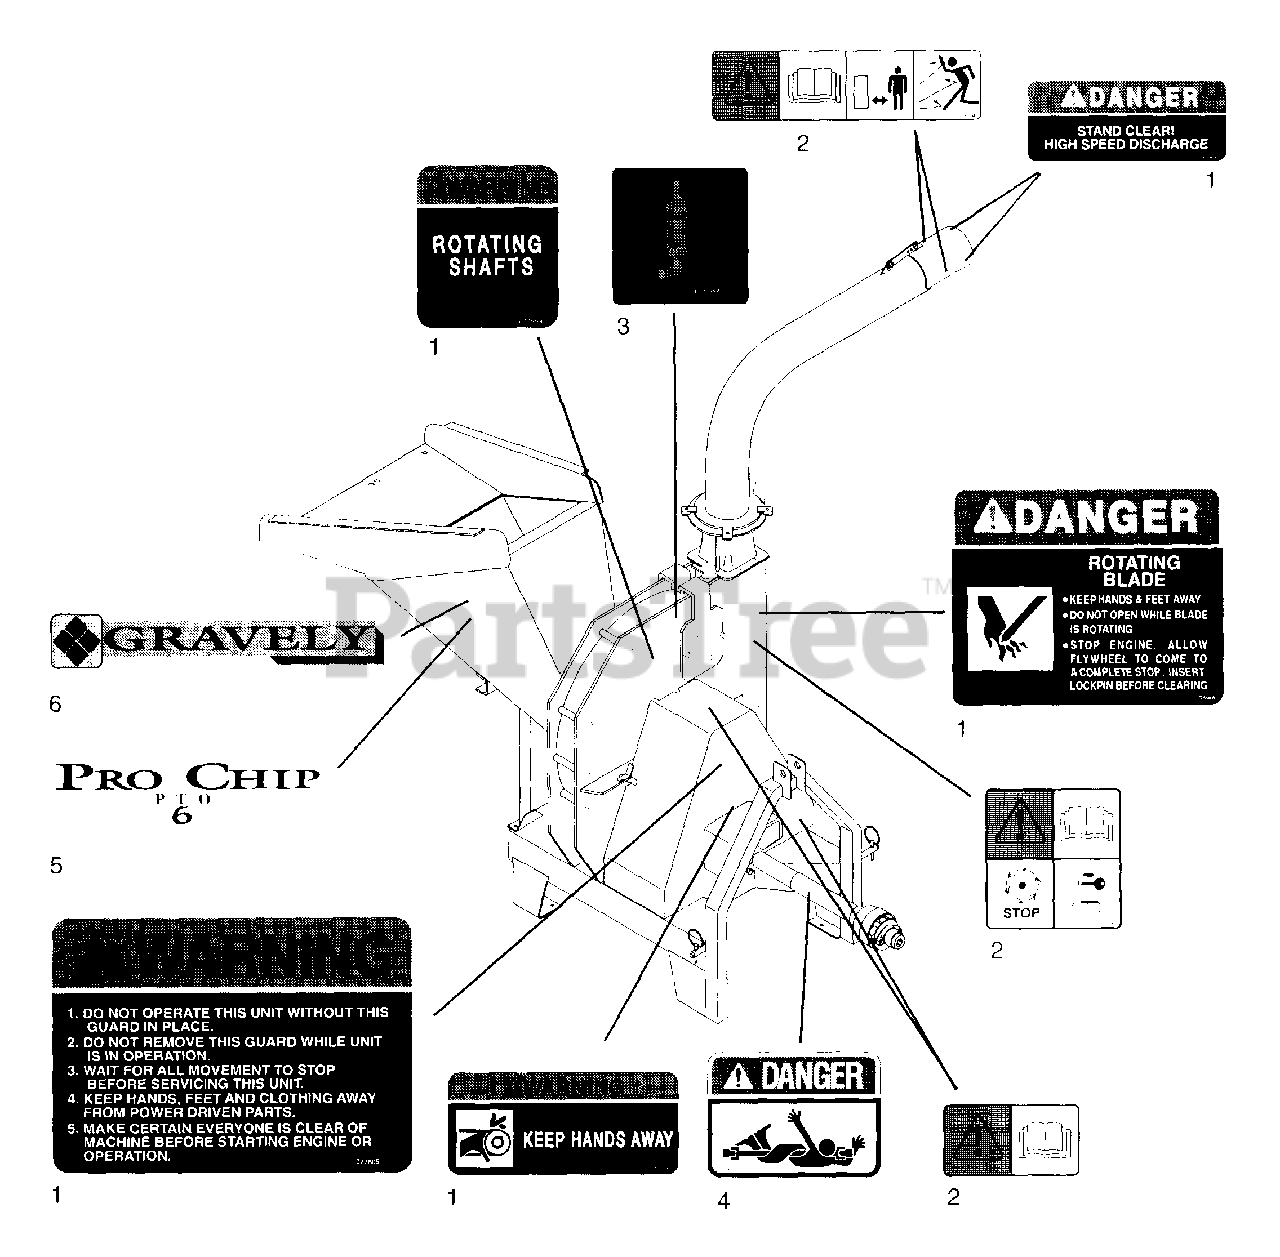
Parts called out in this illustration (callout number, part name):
1	Decal Set-Chipper
2	Decal Set-Chipper
3	Decal-Grease
4	Decal-PTO Warning
5	Decal-Pro Chip Logo
6	Decal-Gravely Logo
7	Decal-Push/Pull
